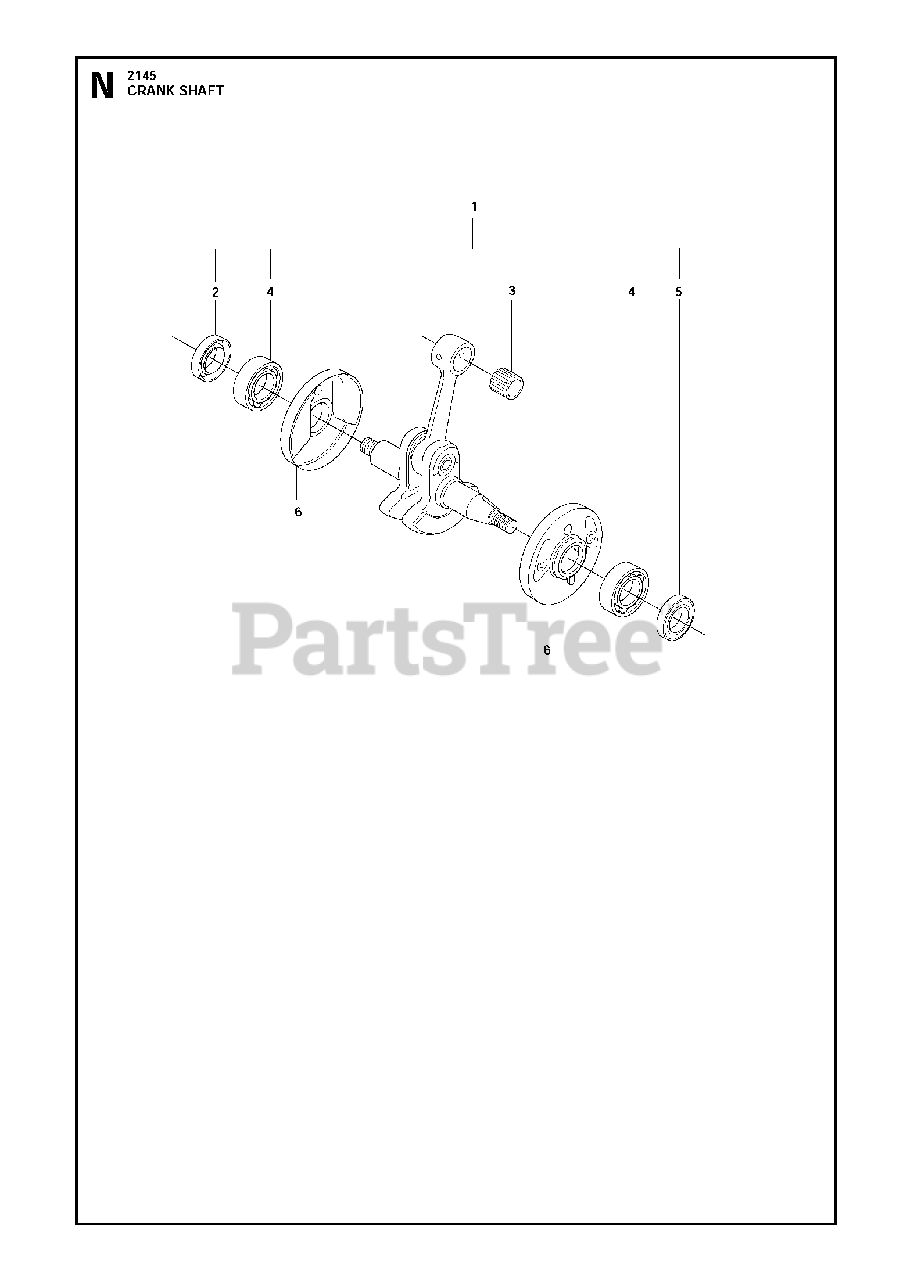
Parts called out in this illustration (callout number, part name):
1	CRANKSHAFT
2	SEALING RING
3	RP SUPPORT BUSHING
4	BALL BEARING-6202-C3 SKF
5	SEAL RING
6	COLLAR
